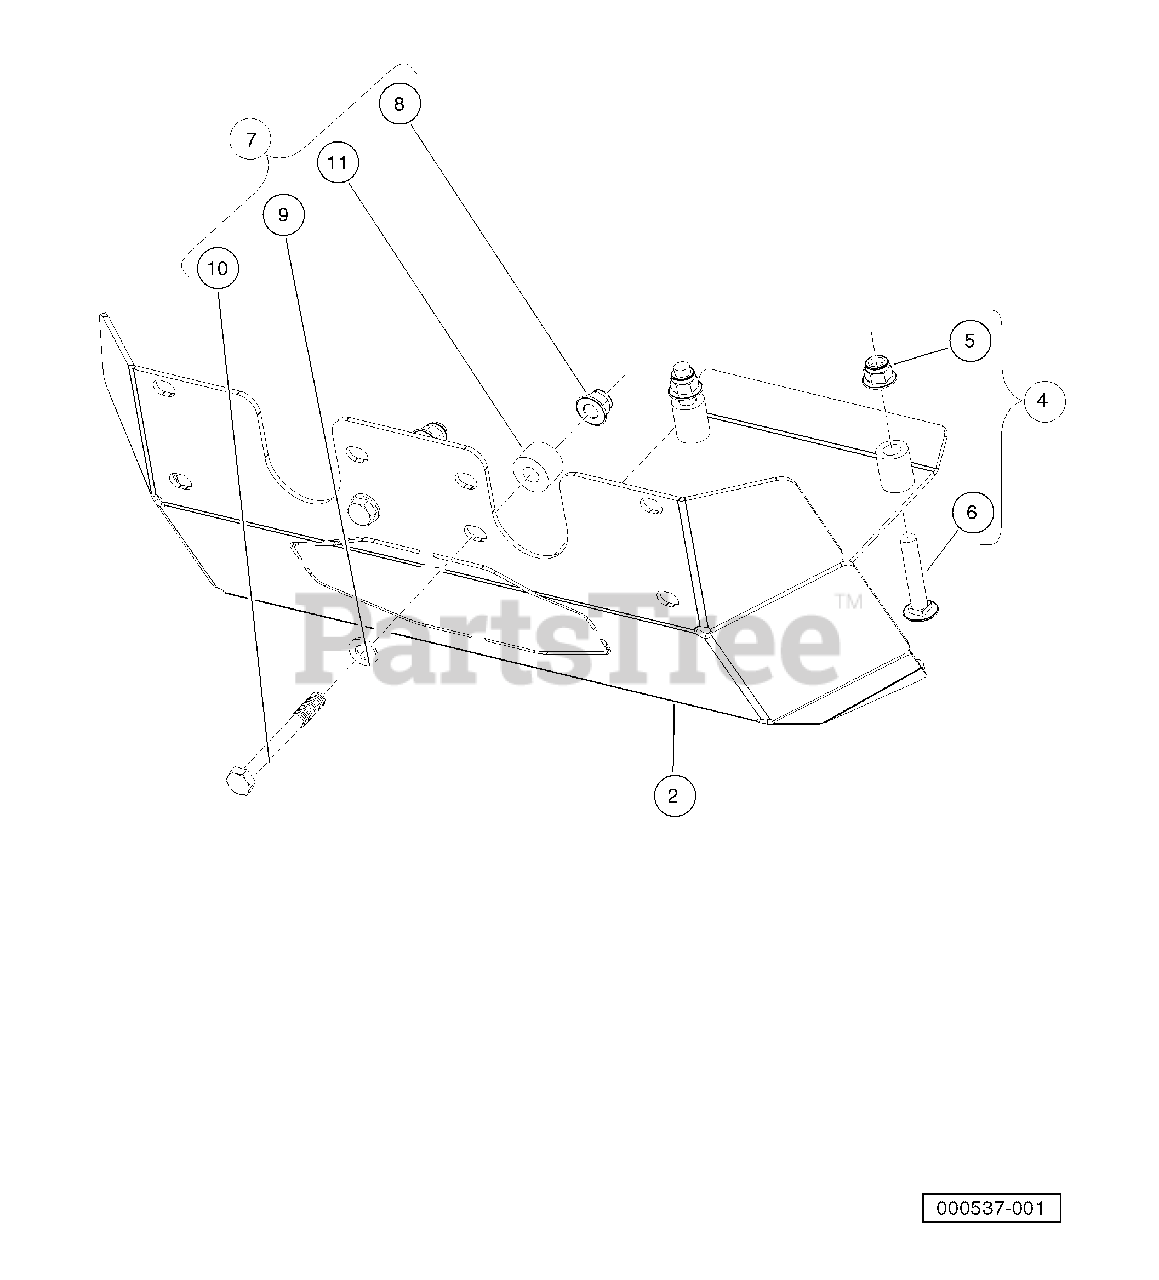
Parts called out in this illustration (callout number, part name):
1	Kit, Skidplate, Front, Steel
2	Skid Plate, Front, Steel
3	Instructions, Front Skidplate
4	Kit, Hardware, Skidplate, Front, A
5	Nut Flg M10 X 1.5 Nylon
6	Bolt, Carriage, M10x1.5x55
7	Kit, Hardware, Skidplate, Front, B
8	Nut Flg M10 X 1.5 Nylon
9	Washer, Hard, M10, Zn-Ni/Blk
10	Bolt, M10 X 1.50 X 90, Loctite
11	Spacer, 17mm Long, Skidplate
